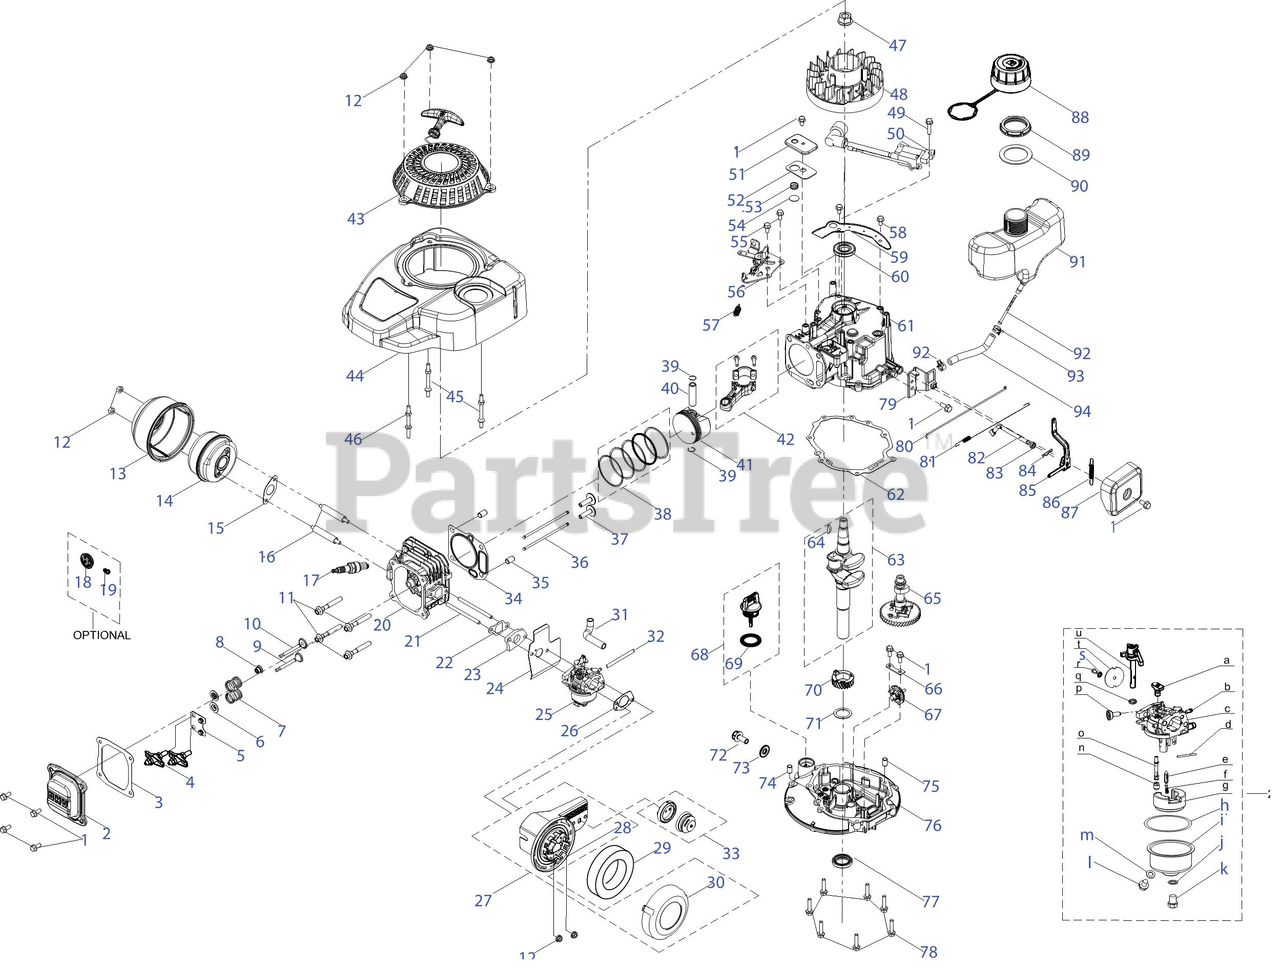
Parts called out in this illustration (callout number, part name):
1	Bolt M6x14
2	Valve Cover
3	Valve Cover Gasket
4	Rocker Arm Assembly
5	Push Rod Guide
6	Valve Spring Retainer
7	Valve Spring
8	Intake Valve Seal
9	Exhaust Valve
10	Intake Valve
11	Bolt M8x54 Cylinder Head
13	Muffler Shield
14	Muffler Assembly
15	Muffler Gasket
16	Muffler Stud M6x76
17	Spark Plug/F5RTC
18	Spark Arrestor
19	Spark Arrestor Screw
20	Cylinder Head
21	Carb Stud M6x98
22	Carburetor Insulator Gasket
23	Carburetor Insulator
24	Carburetor Gasket
25	Carburetor Assembly
26	Air Filter Base Gasket
27	Air Filter Assembly
28	Air Filter Base
29	Air Filter Element, Foam
30	Air Filter Cover
31	Breather Hose
32	Primer Hose
33	Primer Assembly, Vented
34	Cylinder Head Gasket
35	Cylinder Head Dowel Pin 10x16
36	Push Rod
38	Piston Ring Set
39	Piston Pin Snap Ring
40	Piston Pin
41	Piston
42	Connecting Rod Assembly
43	Starter Recoil Assembly
44	Engine Shroud Assembly
45	Shroud Stud M6x75
46	Shroud Stud M6x73
47	Flywheel Nut M14
48	Flywheel
49	Bolt M6x25
50	Ignition Coil Assembly
51	Breather Cover Plate
52	Breather Gasket
53	Breather Valve Spring
54	Breather Valve
55	Bolt M6x12
56	Brake Assembly
57	Brake Spring
58	Bolt M6x10
59	Shroud Cover Plate
60	Upper Crankshaft Seal
62	Crankcase Cover Gasket
63	Crankshaft Assembly
64	Flywheel Key
65	Camshaft Assembly
66	Governor Gear Mounting Plate
67	Governor Gear/Shaft Assembly
68	Dipstick Assembly
69	Dipstick Seal
70	Timing Gear
71	Crankshaft Thrust Washer
72	Oil Drain Plug
73	Oil Drain Plug Washer
74	Crankcase Cover Dowel Pin 9x14
75	Crankcase Cover Dowel Pin 7x14
76	Crankcase Cover
77	Lower Crankshaft Seal
78	Bolt M6x28
79	Component Bracket
80	Throttle Linkage
81	Throttle Linkage Spring
82	Governor Arm Shaft
83	Governor Seal
84	Governor Arm Shaft Cotter Pin
85	Governor Arm Assembly
86	Governor Spring
87	Governor Shield
88	Fuel Cap Assembly
89	Fuel Tank Nut
90	Fuel Tank Upper Grommet
91	Fuel Tank
92	Fuel Filter
93	Fuel Hose Clamp
94	Fuel Hose
